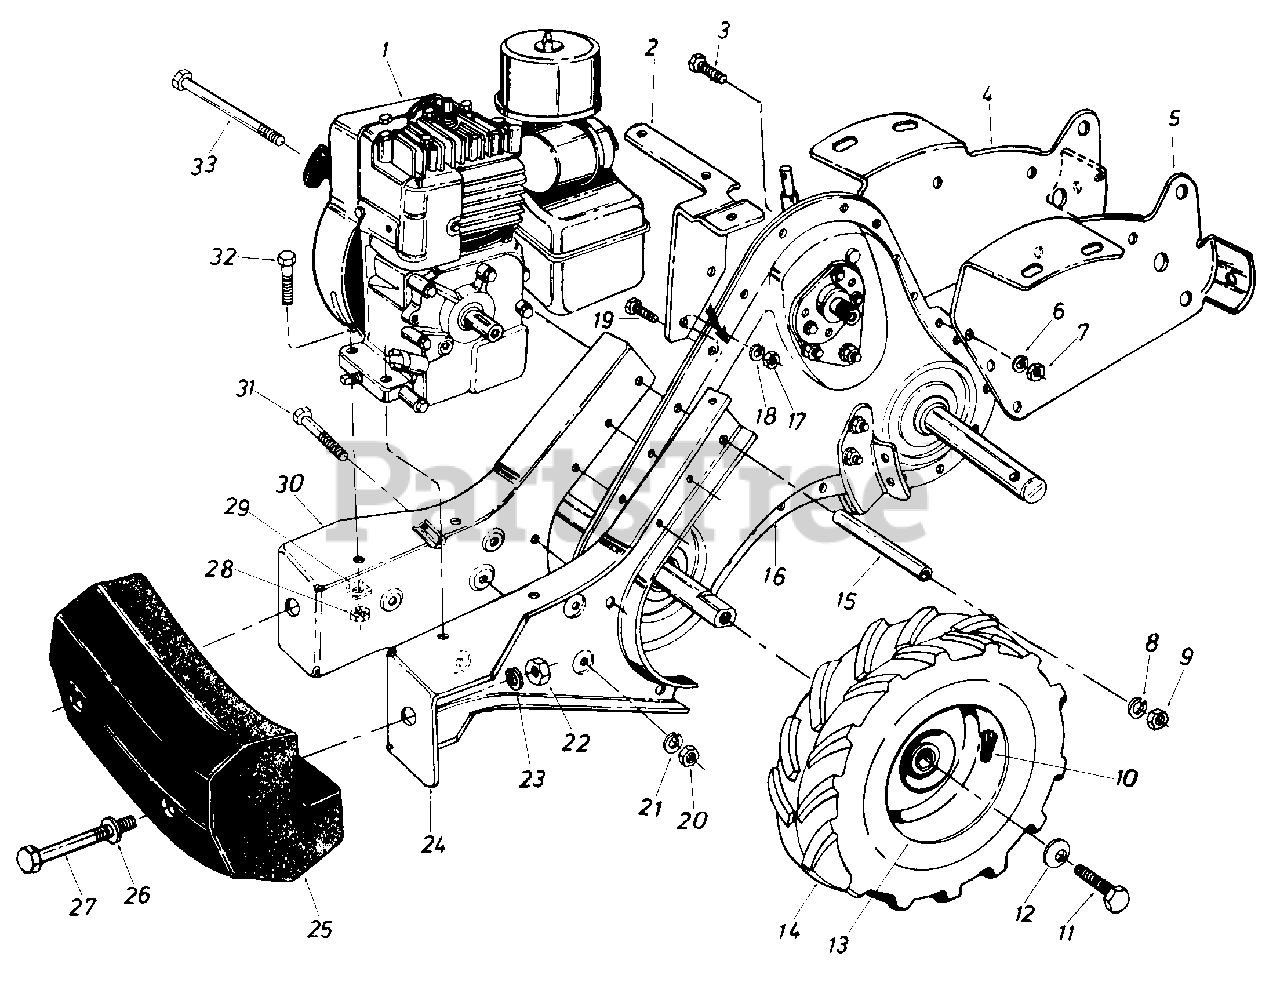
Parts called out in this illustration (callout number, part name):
2	Belt Cover Mounting Brkt.
3	Hex Bolt 3/8-16 x 1.00" Lg.
7	Hex Nut 3/8-16 Thd.
8	L-Wash. 5/16" I.D.
9	Hex Nut 5/16-18" Thd.
10	Air Valve
11	Hex Bolt 5/16-24 x .62" Lg.
12	Bell-Wash. .345" I.D. x .88"
13	Wheel Rim Ass'y. Only
14	L.H. Wheel Ass'y. Comp.
16	Transmission Comp.
17	Hex Nut 5/16-18 Thd.
18	L-Wash. 5/16" I.D.
19	Hex Bolt 5/16-18 x .75" Lg.
20	Hex Nut 3/8-16 Thd.
21	L-Wash. 3/8" I.D. H.D.
22	Hex Nut 1/2-13 Thd.
23	L-Wash. 1/2" I.D.
26	Fl-Wash. .510" I.D. x 1 0"
27	Hex Bolt 1/2-13 x 5.00" Lg.
28	Hex Nut 5/16-18 Thd.
29	L-Wash. 5/16" I.D.
32	Hex Bolt 5/16-18 x 1.50"
33	Hex Bolt 5/16-18 x 4.75" Lg. Gr. 2
